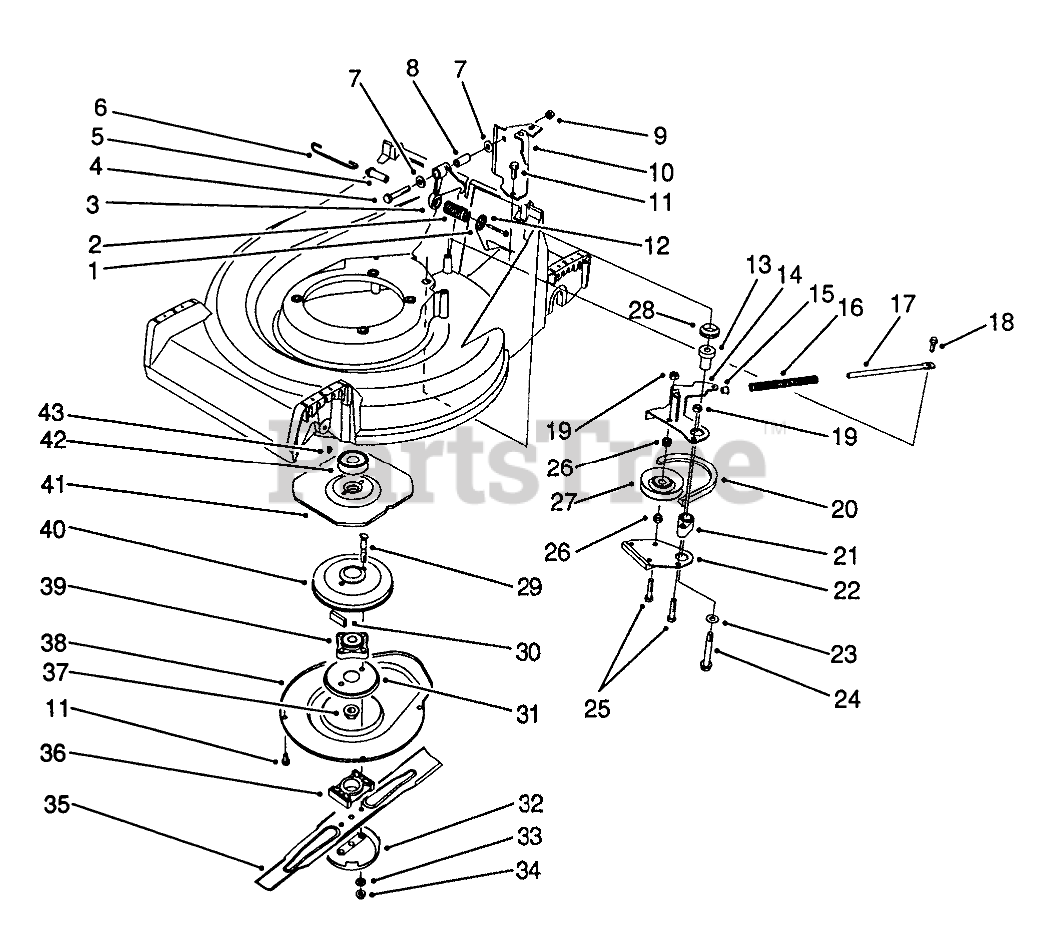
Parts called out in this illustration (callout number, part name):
1	RETAINER-SPRING
2	COMPRESSION SPRING
3	CRANK
4	SCREW-HH
5	SPRING PIN
6	CONTROL LINK
7	WASHER-PLAIN
8	STRAIGHT BUSHING
10	Bracket-Cable Support
11	SCREW-HWHTF
12	SCREW-HWHTF
13	BBC PM BUSHING
14	Lever
15	SPACER
16	COMPRESSION SPRING
17	SPRING ROD
18	SCREW-SHOULDER
19	NUT-LOCK, NI
20	V-BELT
21	BRAKE PLATE HUB
22	BRAKE SHOE
23	WASHER-PLAIN
24	3/8-16 X 2-3/4 CAPSCR
25	SCREW-HH
26	IDLER PULLEY HUB
27	PULLEY-IDLER
28	V-RING SEAL
29	BOLT-BLADE
30	DAMPENER-VIBRATION
31	Screen-BBC
32	Anti Scalp Cup
33	WASHER
34	NUT-LOCK
35	Key
36	SPACER-BLADE
37	NUT-LOCK, NI
38	Cover
39	HUB ASM
40	BRAKE DRUM
41	FLYWHEEL - BBC
42	PULLEY
43	KEY-WOODRUFF
